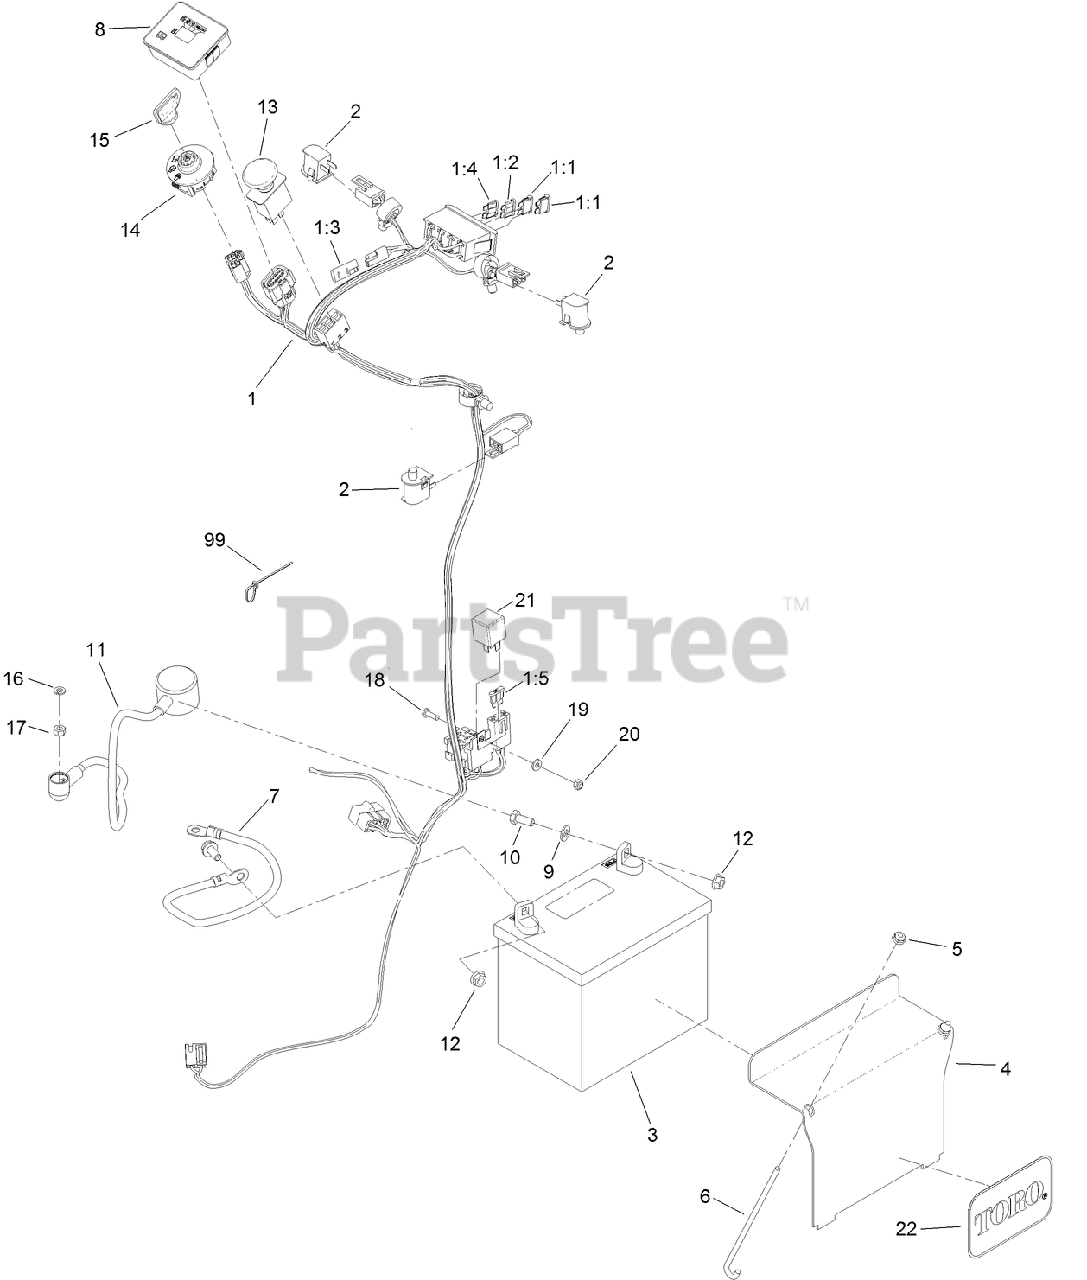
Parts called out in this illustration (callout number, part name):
1	HARNESS-WIRE
1:1	FUSE-BLADE, 15 AMP
1:2	FUSE-BLADE, 10 AMP
1:3	CAP-PLUG
1:4	FUSE-BLADE, 7.5 AMP
1:5	FUSE-BLADE, 30 AMP
2	SWITCH-BAIL
3	BATTERY-DRY
4	BRACKET-HOLD DOWN, BATTERY
5	NUT-HF
6	BOLT-HOLDDOWN
7	CABLE-BATTERY, BLACK
8	MODULE-METER, HOUR
9	WASHER-PLAIN
10	SCREW-HH
11	CABLE-BATTERY, POSITIVE
12	NUT-HHF, SMOOTH
13	SWITCH-PTO, ON-ON-(ON)
14	SWITCH-IGNITION
15	KEY-IGNITION
16	WASHER-LOCK
17	NUT-HEX
18	SCREW-PPH
19	WASHER-FLAT
20	NUT-LOCK, NI
22	DECAL
99	TIE-CABLE
